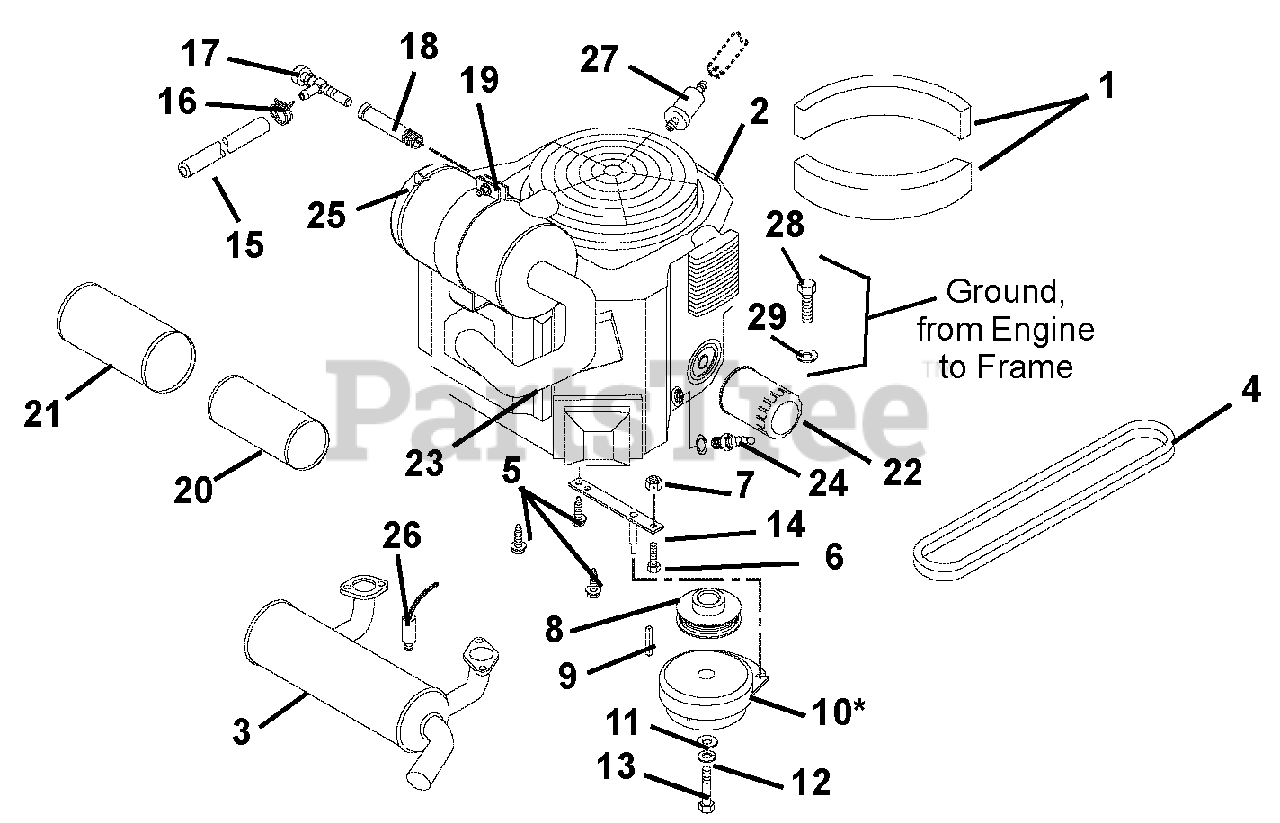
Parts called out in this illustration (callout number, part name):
1	Seal, Foam (045, 046, 047, 052, 066, 067, 068, 071, 087, 088, 089, 091, 102, 107)
2	Engine, Kohler 28HP EFI (091, 107)
3	Muffler, Kohler EFI (091, 107)
4	Belt, Poly-V
5	Screw, Tapping Hex Washer Head .38-16 x 1.00 (045, 046, 047, 052, 066, 067, 068, 071, 087, 088, 089,
6	Bolt, Hex .31-18 x 1.75 Grade 5 (045, 046, 047, 052, 066, 067, 068, 071, 087, 088, 089, 091, 102, 107)
7	Nut, Locking Top Flange .31-18
8	Sheave, Poly V 1.127 x 3.25
9	Key, Square .25 x 1.00 x .25
10	Clutch, Electric
11	Washer, Flat Steel .515 x 1.625 x .250
12	Washer, Locking .44 x .109
13	Bolt, Hex .44-20 x 3.00 Grade 5
14	Anchor, Clutch
15	Gas Line, Bulk .25 ID (045, 046, 047, 052, 066, 067, 068, 071, 084, 085, 086, 087, 088, 089, 102, 103,
16	Hose, Clamp
17	Cock, Oil Drain
18	Adapter, Oil Drain
19	Bracket, Air Cleaner Mount
20	Element, Inner Safety
21	Element, Outer Primary
22	Oil Filter (047, 052, 068, 071, 087, 089, 091, 107)
23	Hose, Air Intake (047, 052, 068, 071, 087, 089, 091, 107)
24	Spark Plug (047, 052, 068, 071, 087, 089, 091, 107)
25	Assembly, Air Cleaner
26	Sensor, Oxygen (091, 107)
27	Fuel Filter (045, 046, 066, 067, 088, 102)
28	Bolt, Hex .31-18 x .75
29	Washer, Lock .31 x .078
